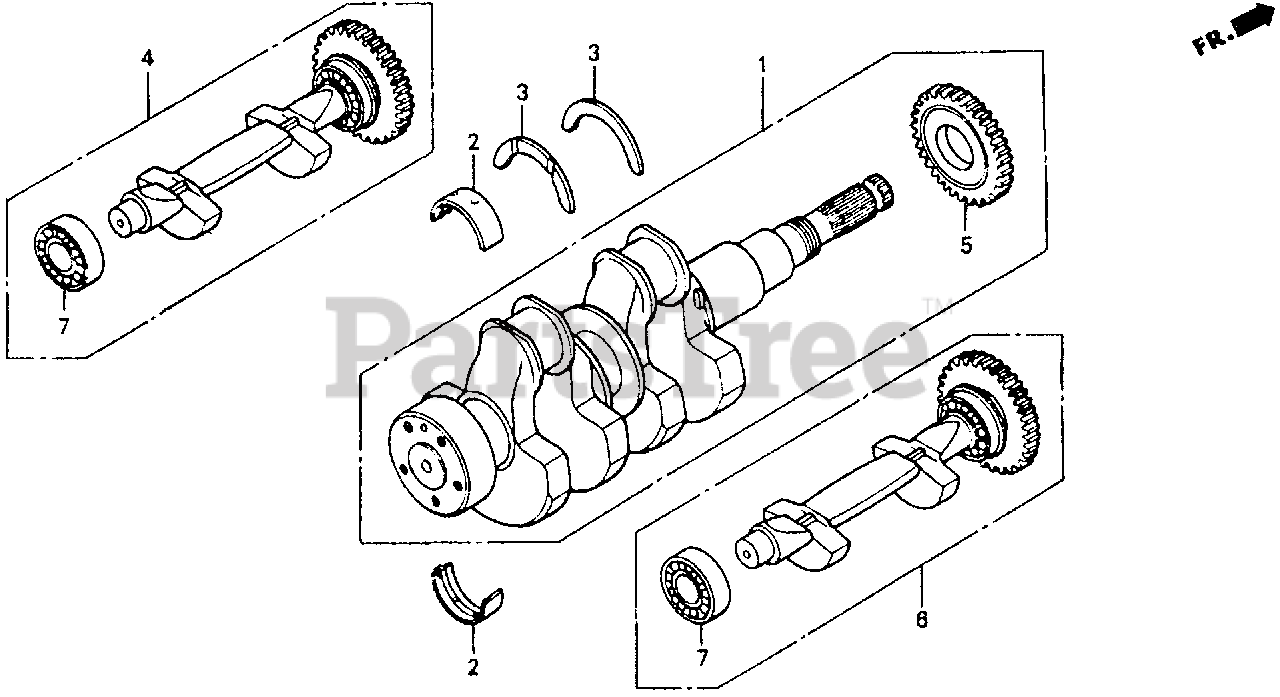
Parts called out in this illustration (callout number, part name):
1	CRANKSHAFT
2	BEARING A, MAIN (BLUE)
2	BEARING B, MAIN (BLACK)
2	BEARING C, MAIN (BROWN)
2	BEARING D, MAIN (GREEN)
2	BEARING E, MAIN (YELLOW)
2	BEARING F, MAIN (PINK)
2	BEARING G, MAIN (RED)
3	WASHER, THRUST
4	WEIGHT, R. BALANCER
5	GEAR, BALANCER DRIVE (48T)
6	WEIGHT, L. BALANCER
7	BEARING, RADIAL BALL (6203)
